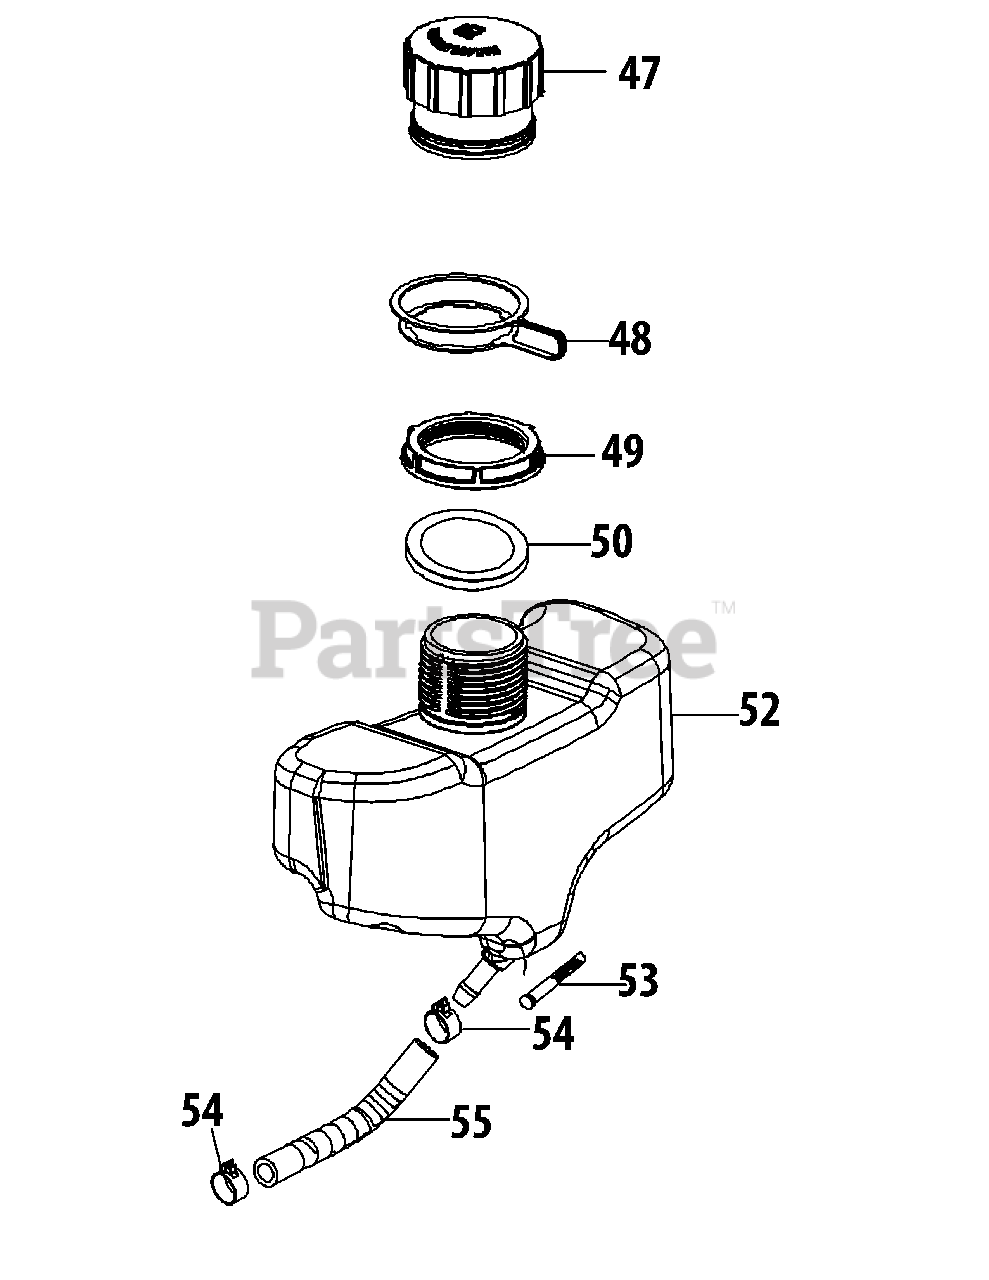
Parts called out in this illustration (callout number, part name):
47	Fuel Cap Assembly
48	Fuel Cap Tether
49	Fuel Tank Nut
50	Fuel Tank Upper Grommet
52	Fuel Tank
53	Fuel Filter
54	Fuel Hose Clamp
55	Fuel Hose
